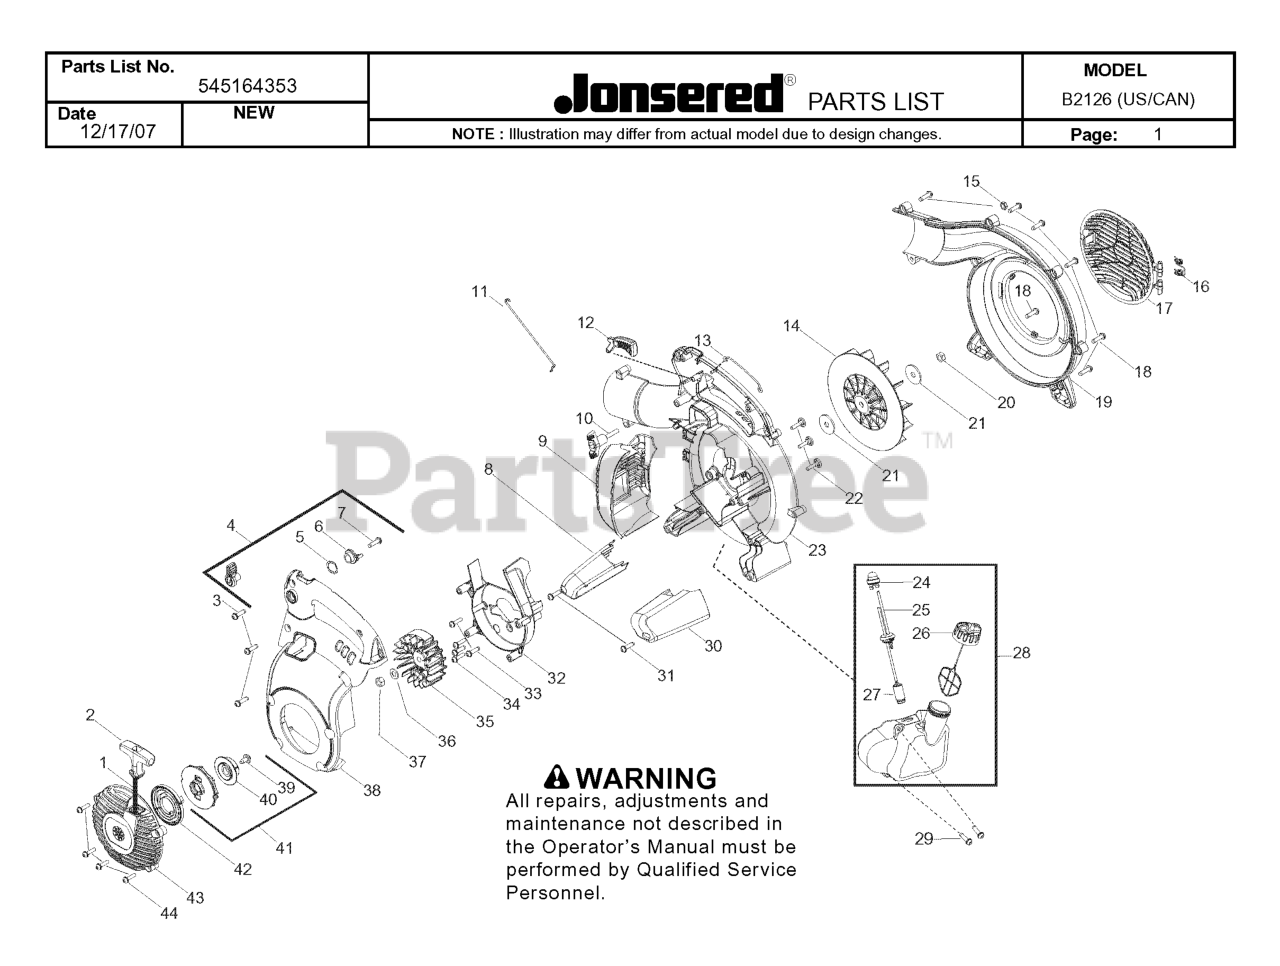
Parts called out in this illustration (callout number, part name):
2	HANDLE - STARTER
4	KIT - CRUIS CONTROL (5,6,7)
6	RATCHET CRUISE CONTROL
8	FOOT - FRONT IMPACT
9	ASSY - MUFFLER GUARD
10	ASSY - TUBE CLAMP
11	WIRE LINKAGE
12	TRIGGER - THROTTLE
13	WIRE, HANDLE GROUND
16	SPRING, VAC DOOR
17	COVER VAC DOOR BLACK
20	NUT, IMPELLER
21	WASHER IMPELLER
22	SCREW FUEL TANK RETAINER
23	SCROLL - INNER
24	AIR PURGE
25	KIT FUEL LINE GROMMET
26	ASSY - FUEL CAP W/RETAINER
27	FUEL PICK-UP ASSY
28	ASSY - FUEL TANK 26,27,28,29
30	FOOT - REAR IMPACT
32	SCROLL, FLYWHEEL
34	SCREW - SHROUD
35	ASSY, FLYWHEEL
36	WASHER FLAT
37	NUT-FLYWHEEL
38	COVER - MOTOR HOUSING
41	KIT - STARTER
42	SPRING STARTER
43	HOUSING - STARTER COVER
44	SCREW - SHROUD
